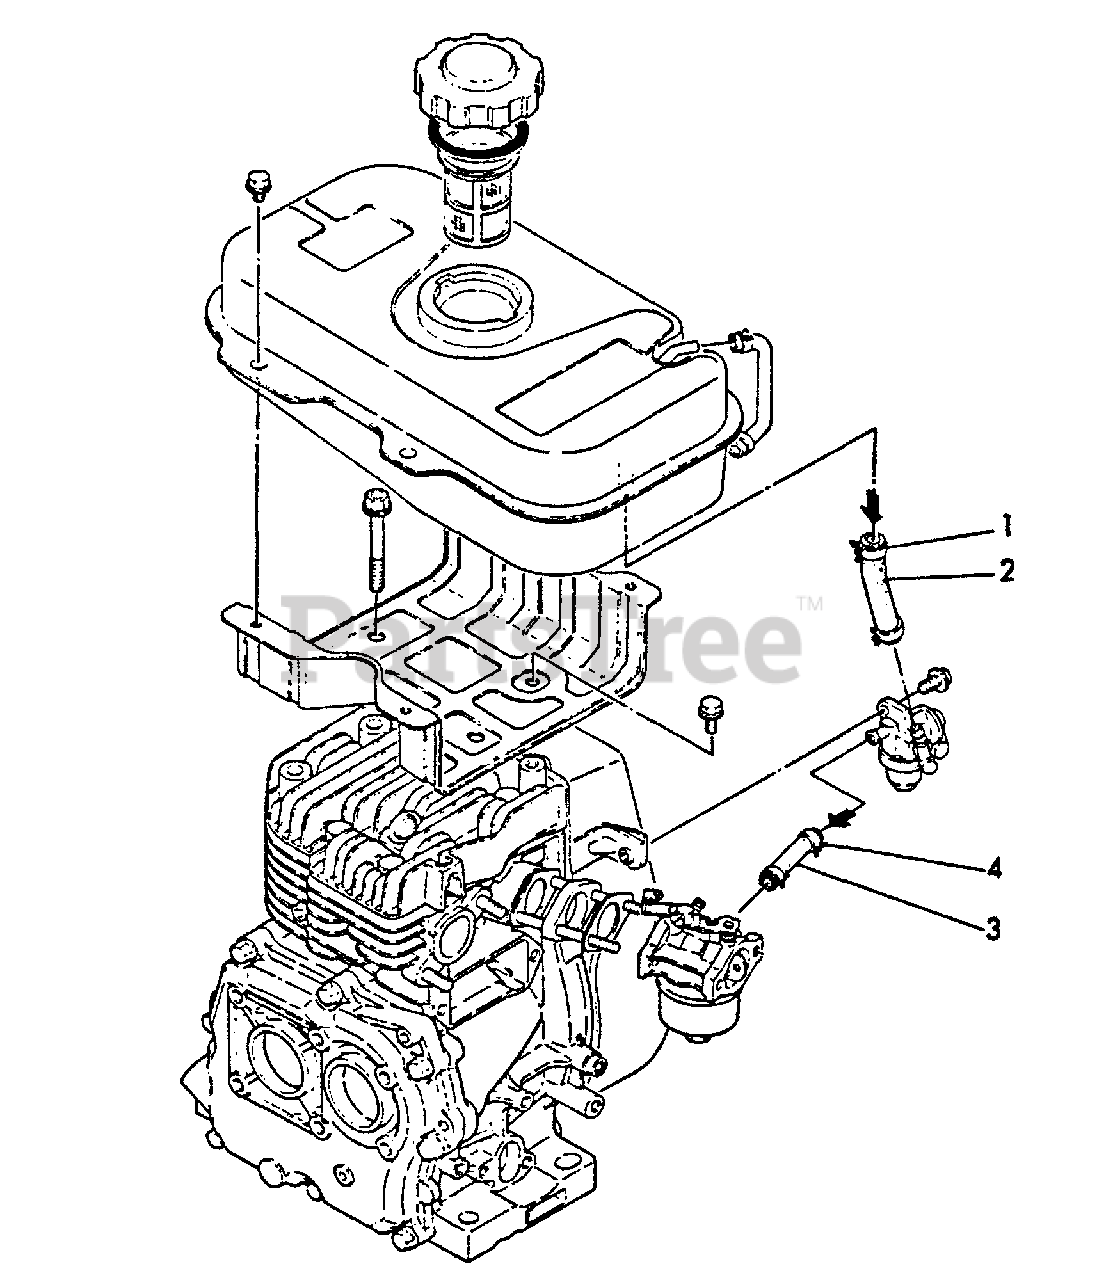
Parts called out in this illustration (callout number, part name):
1	CLAMP, HOSE
2	PIPE - FUEL -- A
3	PIPE - FUEL
4	CLAMP, HOSE - 10
